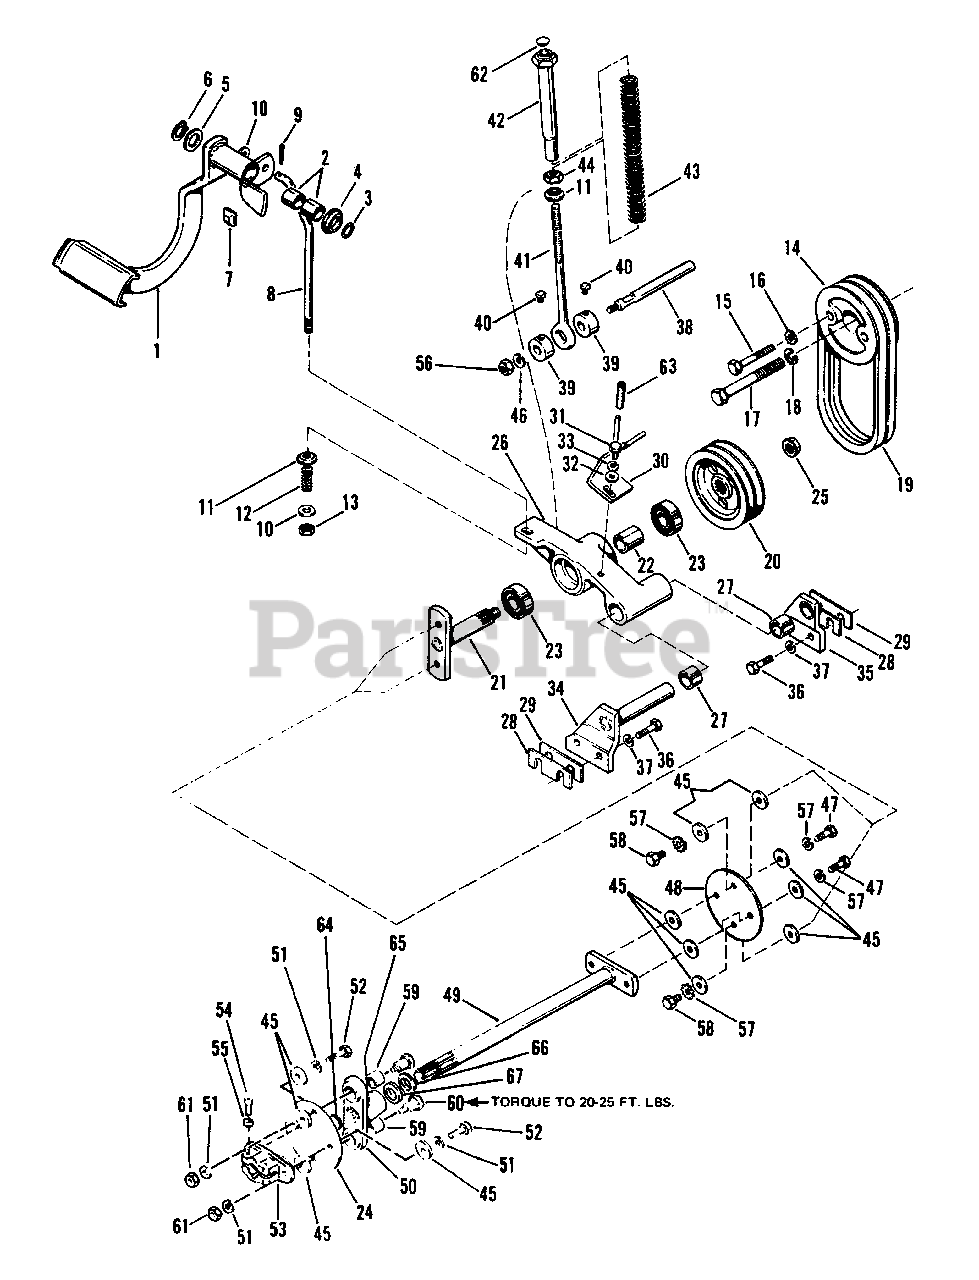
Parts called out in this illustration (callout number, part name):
1	Lever Assembly
2	Bearing Sleeve
3	Retaining Ring
6	Retaining Ring
8	Clutch Rod
9	Cotter Pin
10	Plain Washer, 3/8"
11	Clutch Spacer
13	Hex Nut, Lock, 3/8"-16
14	Input Pulley
15	Hex Capscrew, 3/8"-16 x 2-3/4" lg.
16	Lock Washer, 3/8"
17	Hex Capscrew, 7/16"-14 x 4-1/2" lg.
18	Lock Washer, 7/16"
19	Matched "V" Belts
20	Input Pulley
21	Shaft Assembly
25	Washer Base Lock Nut
26	Pivot Arm
27	Bearing Sleeve
30	Belt Stop
31	Hex Capscrew, 5/16"-18 x 3/4" lg.
32	Plain Washer
33	Lock Washer
34	Support Assembly
35	Support Assembly
36	Hex Capscrew, 3/8"-16 x 1-1/4" lg.
37	Lock Washer, 3/8"
38	Pivot Shaft
40	Set Screw, 5/16"-18 x 5/16" lg.
42	Tube Assembly
44	Hex Nut, Jam, 3/8"-16
45	Special Washer
46	Look Washer, 3/8"
47	Hex Capscrew, 3/8"-16 x 7/8" lg.
49	Drive Shaft Assembly
51	Lock Washer, 3/8"
52	Hex Capscrew, 3/8"-16 x 1" lg.
53	Clamp Yoke
54	Socket Hd. Screw, 5/16"-18 x 1-1/4" lg.
55	Lock Washer, 5/16"
56	Hex Nut, Full, 3/8"-16
57	Shake Proof Lock Washer, 3/8"
58	Hex Capscrew, 3/8"-16 x 7/8" lg.
60	Shoulder Bolt
62	Hole Plug
63	Fuel Line
65	Grease Fitting
67	Felt Washer
